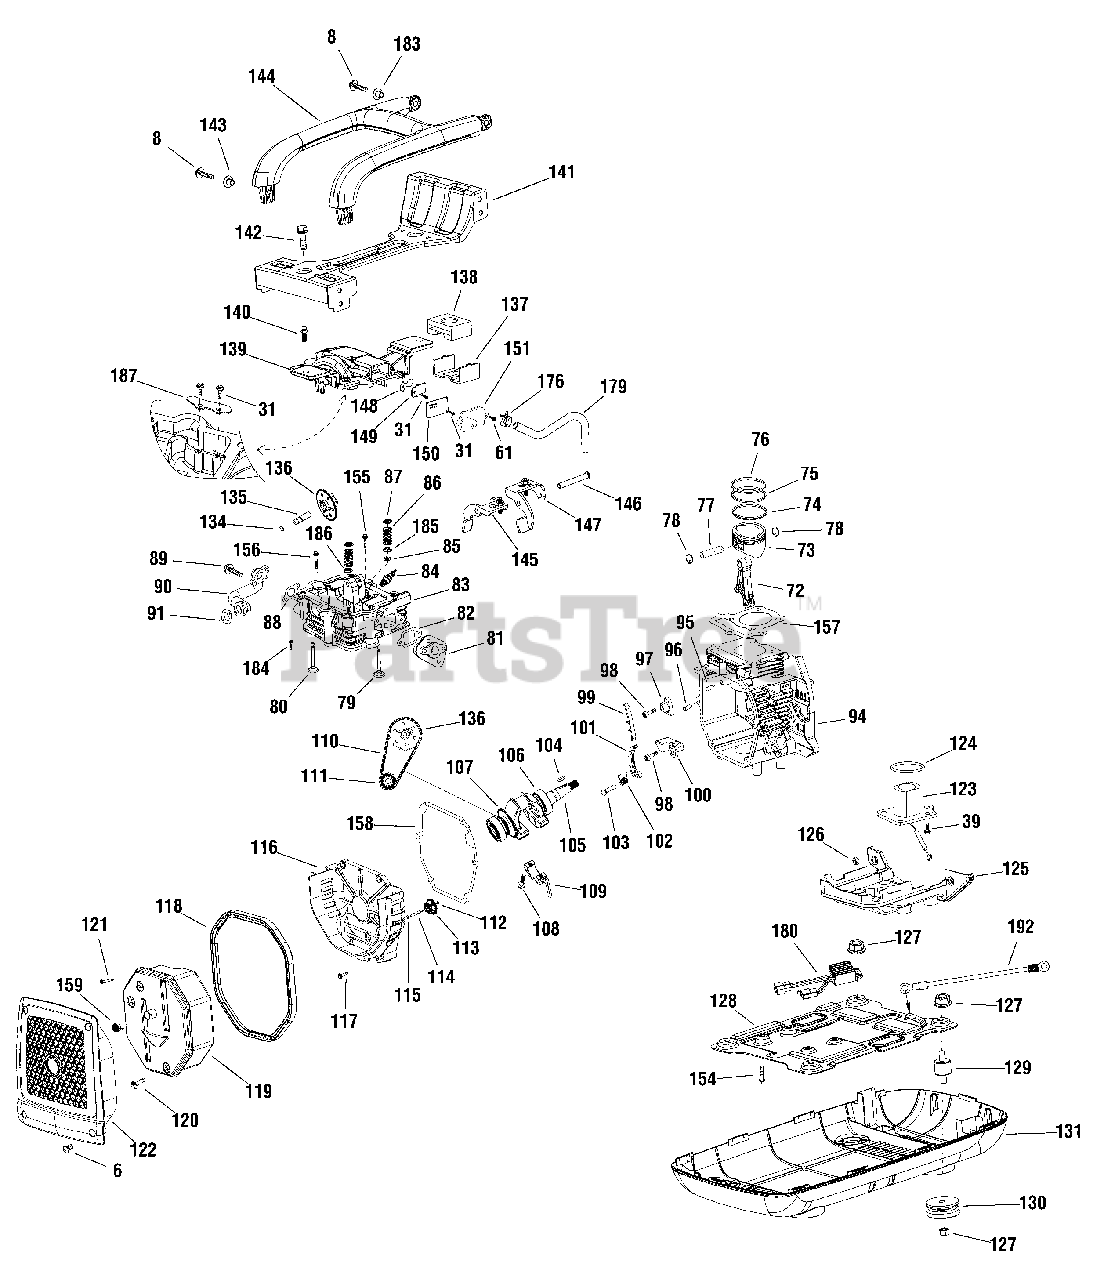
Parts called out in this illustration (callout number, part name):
31	BOLT
61	SCREW
72	ROD
73	PISTON
74	RING
75	RING
76	RING
77	PIN
78	RETAINER, Pin
79	VALVE, Intake
80	VALVE, Exhaust
83	CYLINDER HEAD
85	SEAL, Valve Oil
86	SPRING
87	SEAT, Valve
89	BOLT
90	MUFFLER
91	GASKET, Exhaust
94	CRANKCASE
95	PIN
96	PIN
97	BLOCK
98	SCREW
99	BRACKET
100	BRACKET
101	ARM, Tension
102	SPRING
103	PIN
104	KEY
105	CRANKSHAFT
106	BEARING
107	GEAR
108	BOLT
109	COVER
110	CHAIN
111	WHEEL, Chain
112	SPRING
113	WHEEL, Oil
114	SHAFT
115	SHIM
116	COVER, Crankcase
117	BOLT
118	BLOCK-RUBBER
119	MUFFLER
120	BOLT
121	BOLT
124	O-RING, 33.5 x 2.65
125	COVER
126	NUT
127	NUT
129	MOUNT, Vibration
130	MOUNT, Vibration
134	O-RING
135	SHAFT
136	CAM, Assembly
137	BRACKET
138	MOUNT, Vibration
139	COVER, Cylinder
140	BOLT
141	BRACKET
142	BOLT
145	ARM, Exhaust Valve
146	PIN
147	ARM, Intake valve
150	BOARD, Valve
151	BOARD, Valve
154	BOLT
155	BOLT
156	BOLT
157	GASKET
158	GASKET, Crankcase
159	ARRESTOR, Spark
176	CLAMP
180	REGULATOR, Voltage
184	BOLT
185	SEAT
186	SEAT
187	PLATE
